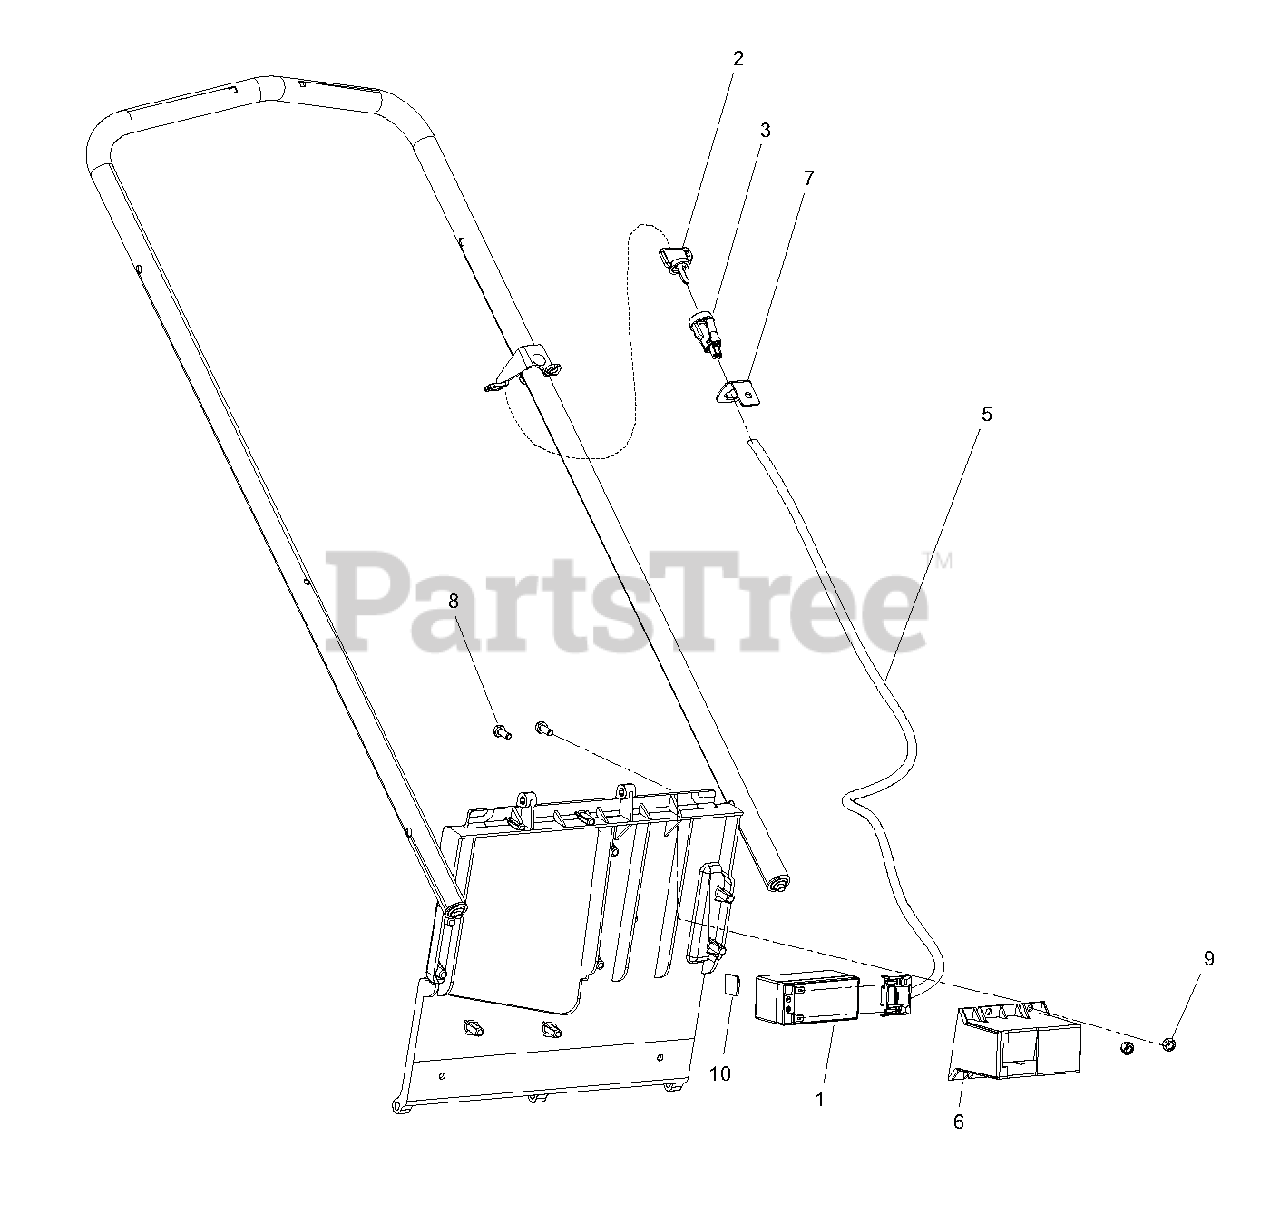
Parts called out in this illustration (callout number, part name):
1	BATTERY,LM(SEE BULLETIN B2117)
2	KEYS, IGNITION
3	SWITCH, KEY
5	HARNESS, ELEC START - LONCIN
6	COVER, BATTERY
7	BRKT, KEY SWITCH
8	BLT-HEX .25-20X.63 GR5 YWZC
9	@NUT-LK-CTR .25-20 YWZC
11	CHARGER, BATTERY
